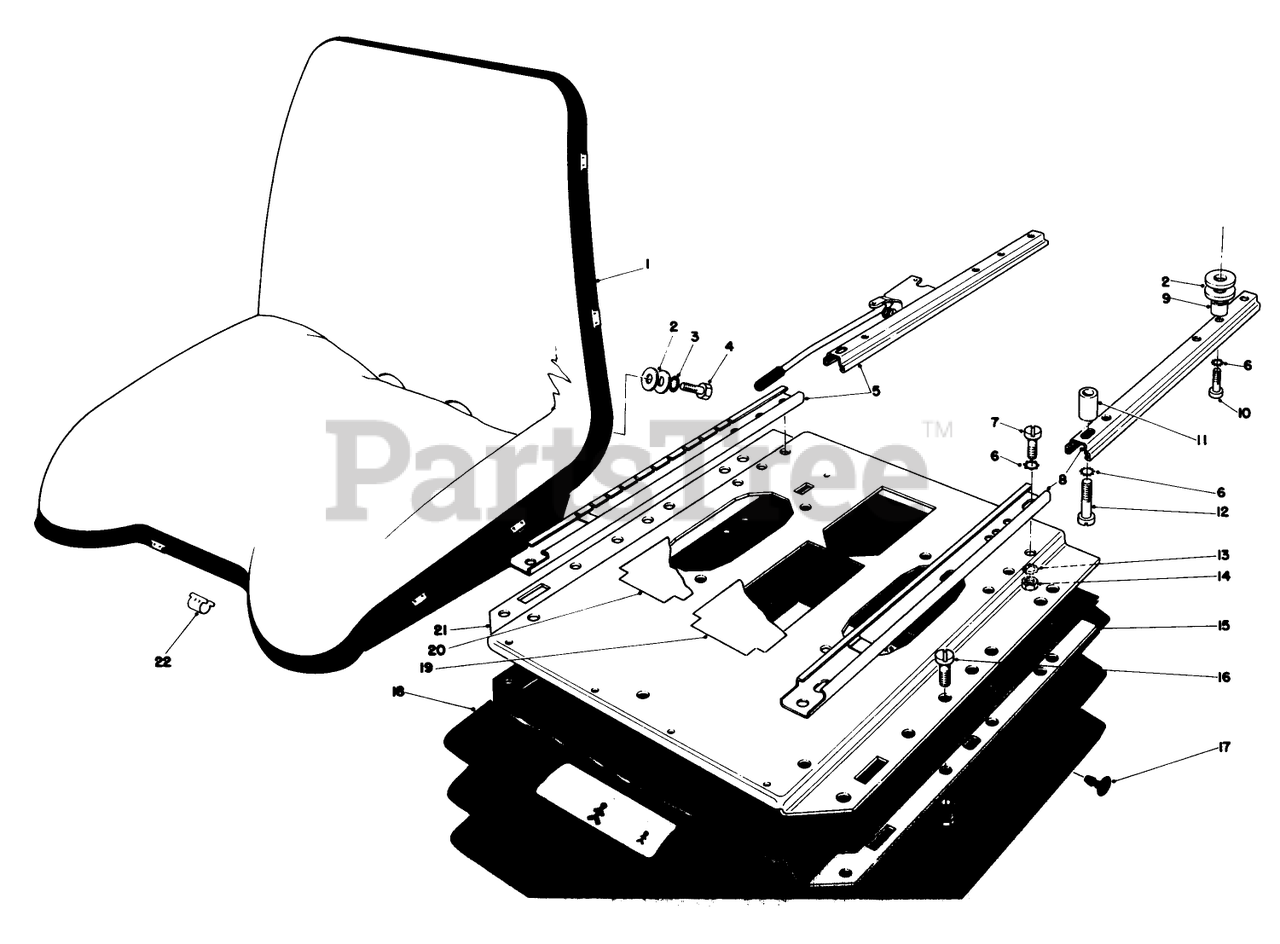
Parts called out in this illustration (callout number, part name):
1	BUCKET SEAT
2	13 MM WASHER
3	SERRATED WASHER
4	HEX HD CAPSCREW
5	ADJ TRACK & LATCH
6	SERRATED WASHER
7	Cylinder Bolt M8X16
8	ADJ TRACK
9	SLEEVE
10	CYL BOLT
11	SLEEVE
12	CYL BOLT
13	SPRING WASHER
14	Nut M8
16	CAPSCREW
17	PLUG-PLASTIC
18	BELLOWS
19	CENTER COVER
20	COVER
21	Upper Suspension Plate Complete
22	OUTSIDE CLAMP
